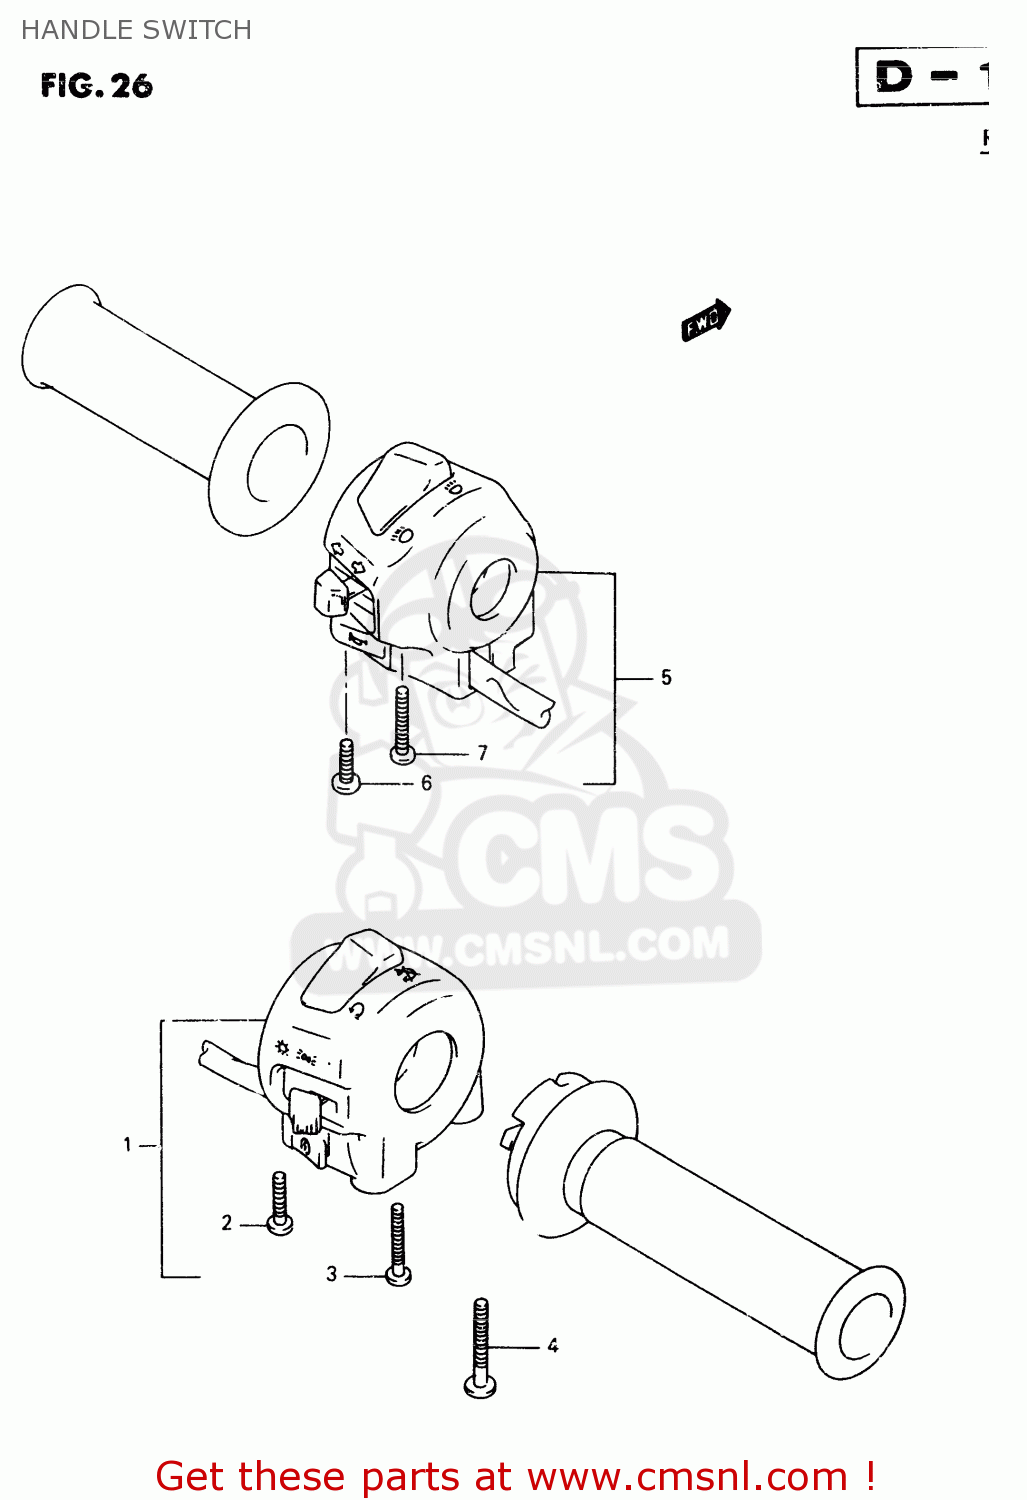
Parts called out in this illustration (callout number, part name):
1	SWITCH ASSY,HANDLE,R
2	SCREW
3	SCREW
4	SCREW
5	SWITCH ASSY,HANDLE,L
6	SCREW
7	SCREW
